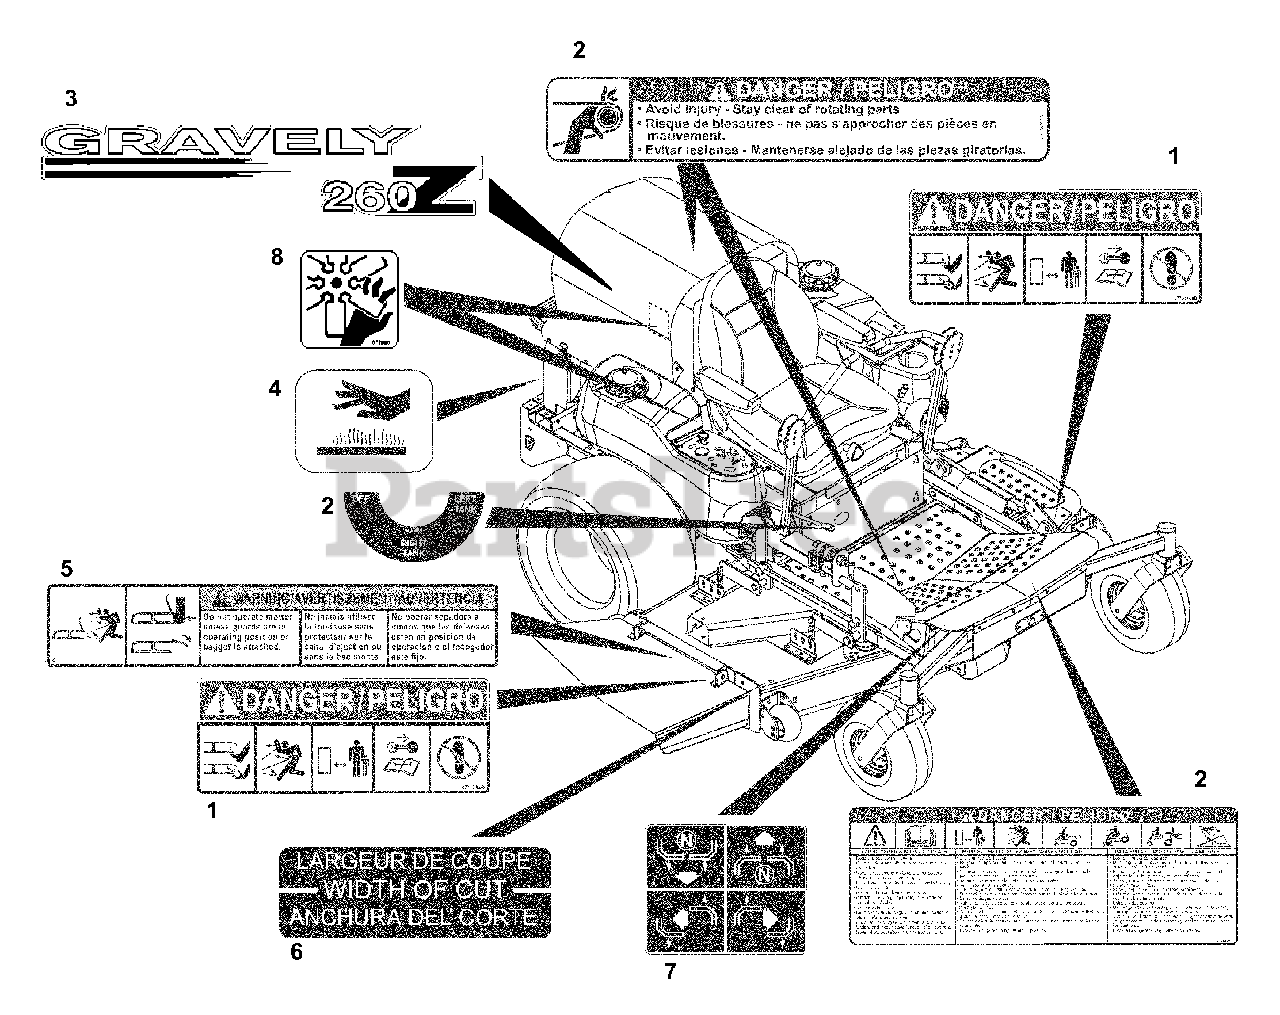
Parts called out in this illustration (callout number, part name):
1	Decal, Mower Pan Head Danger
2	Set, Decal-Common Danger/Fuel
3	Decal, PM-260Z Hood
3	Decal, PM-272Z Hood
4	Decal, Hot Surface
5	Decal, Warning
6	Decal, Width of Cut
7	Decal, Instructional
8	Decal, Danger Fan
